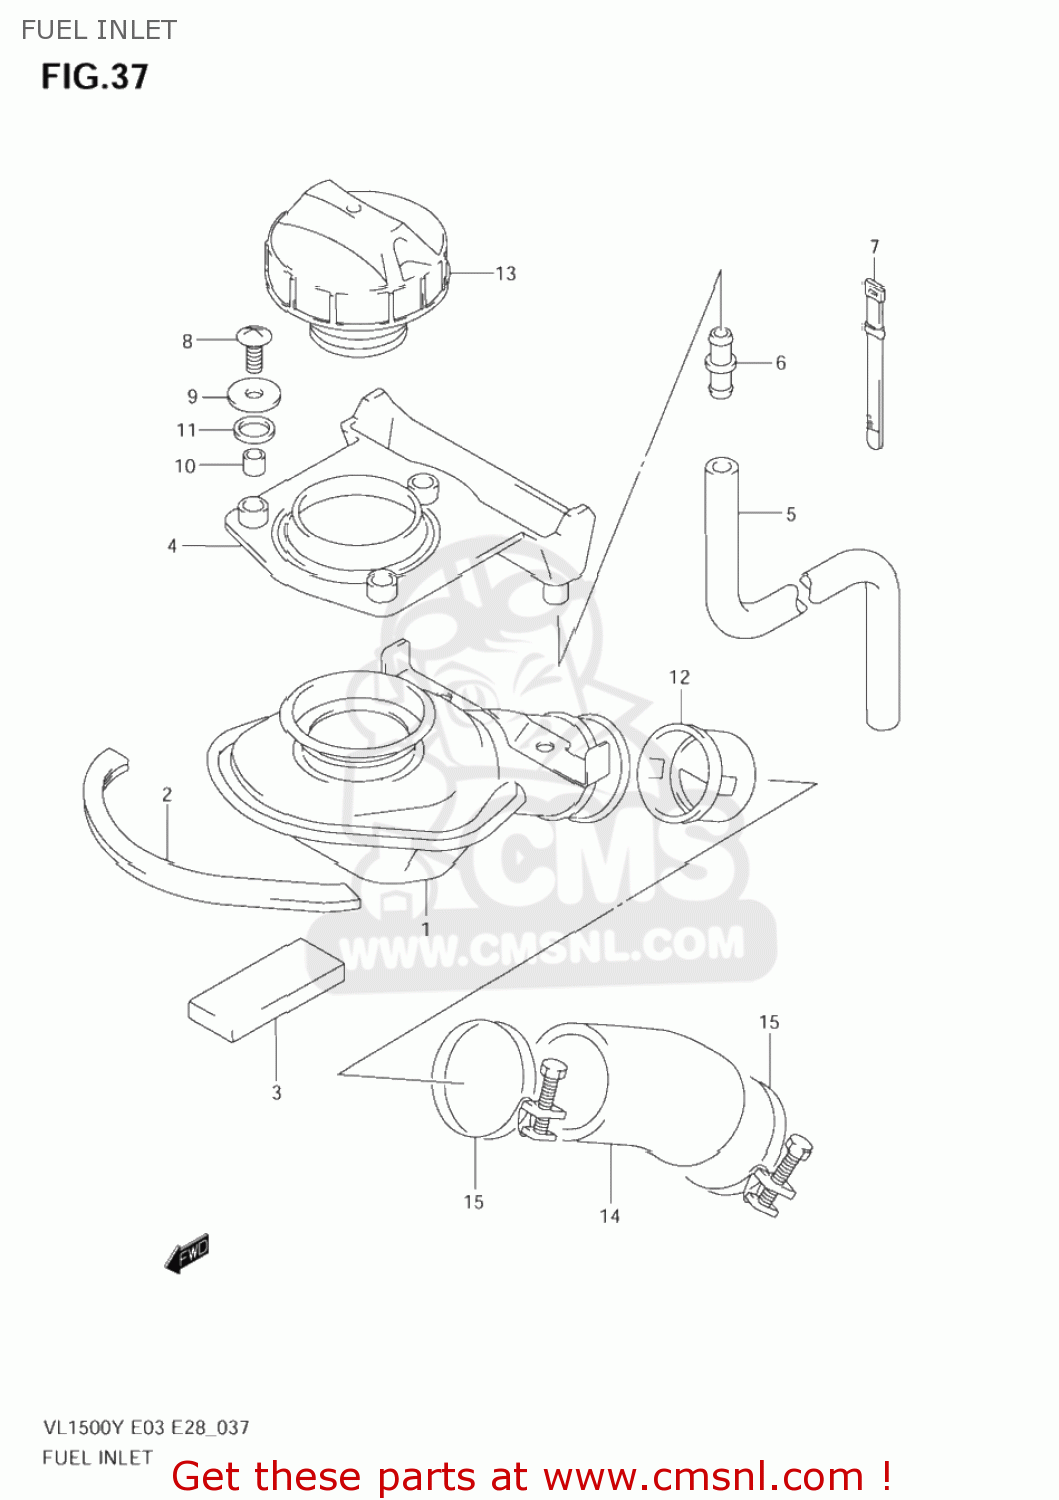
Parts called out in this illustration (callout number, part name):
1	INLET,FUEL TANK
2	MOLDING
3	CUSHION
4	TRAY,FUEL TANK INLET
5	HOSE(7X10.2X2000)
6	JOINT
7	CLAMP(L:165)
8	SCREW
9	WASHER(5.5X20X1.4)
10	SPACER(5.5X8X7.5)
11	CUSHION,FUEL TANK INLET UPR
12	VALVE,FUEL TANK INLET
13	CAP ASSY,FUEL TANK
14	HOSE,FUEL TANK FILLER
15	CLAMP
